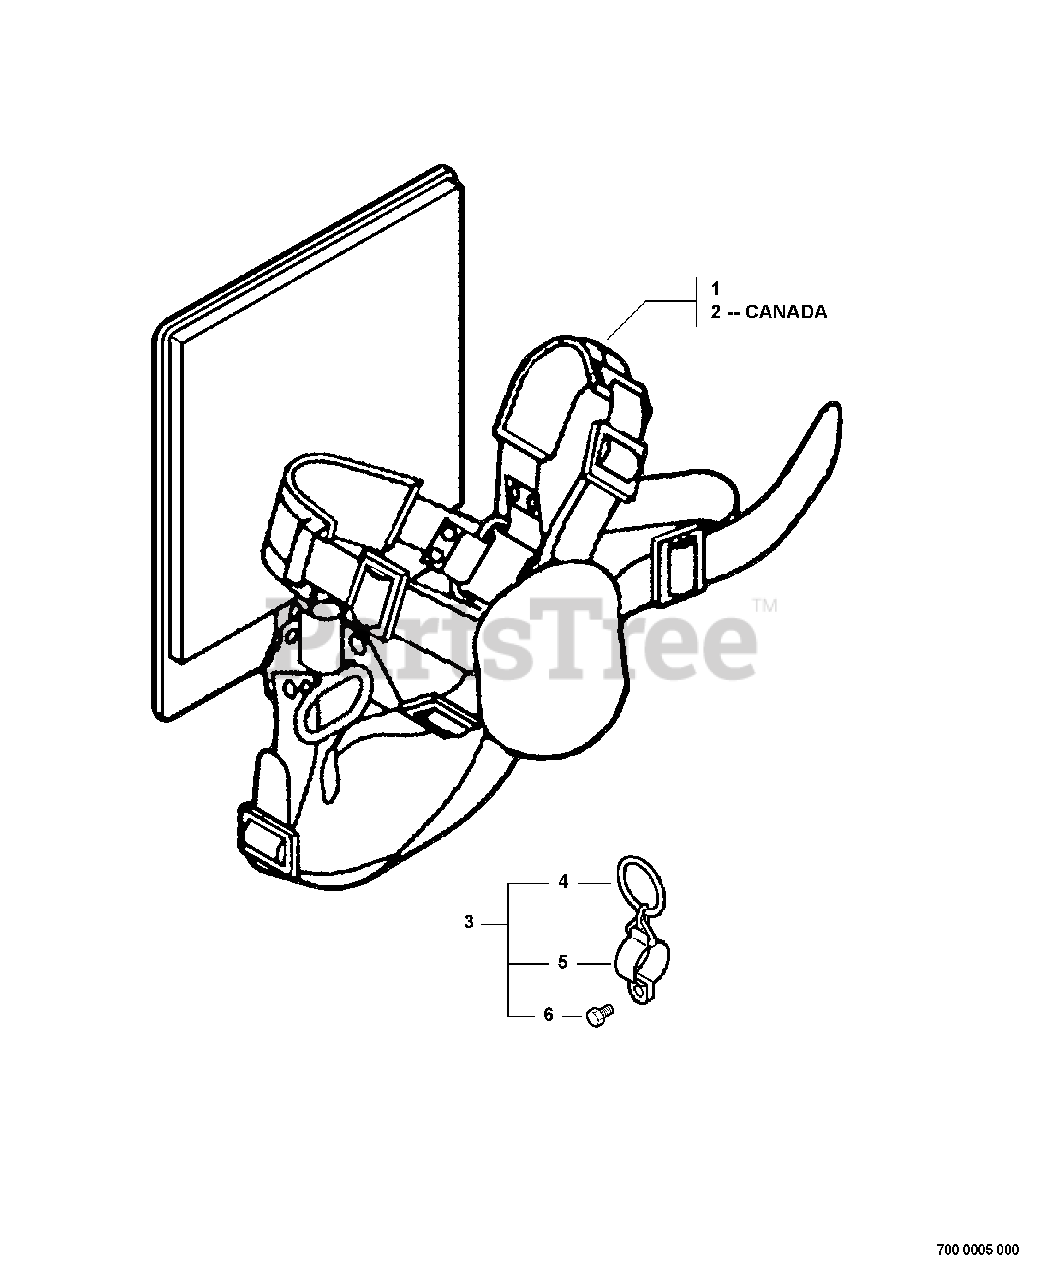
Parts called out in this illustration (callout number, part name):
1	SHOULDER STRAP ASSY
2	SHOULDER STRAP ASSY
3	HANGER ASSY
5	CLAMP
6	SCREW - 5X12
